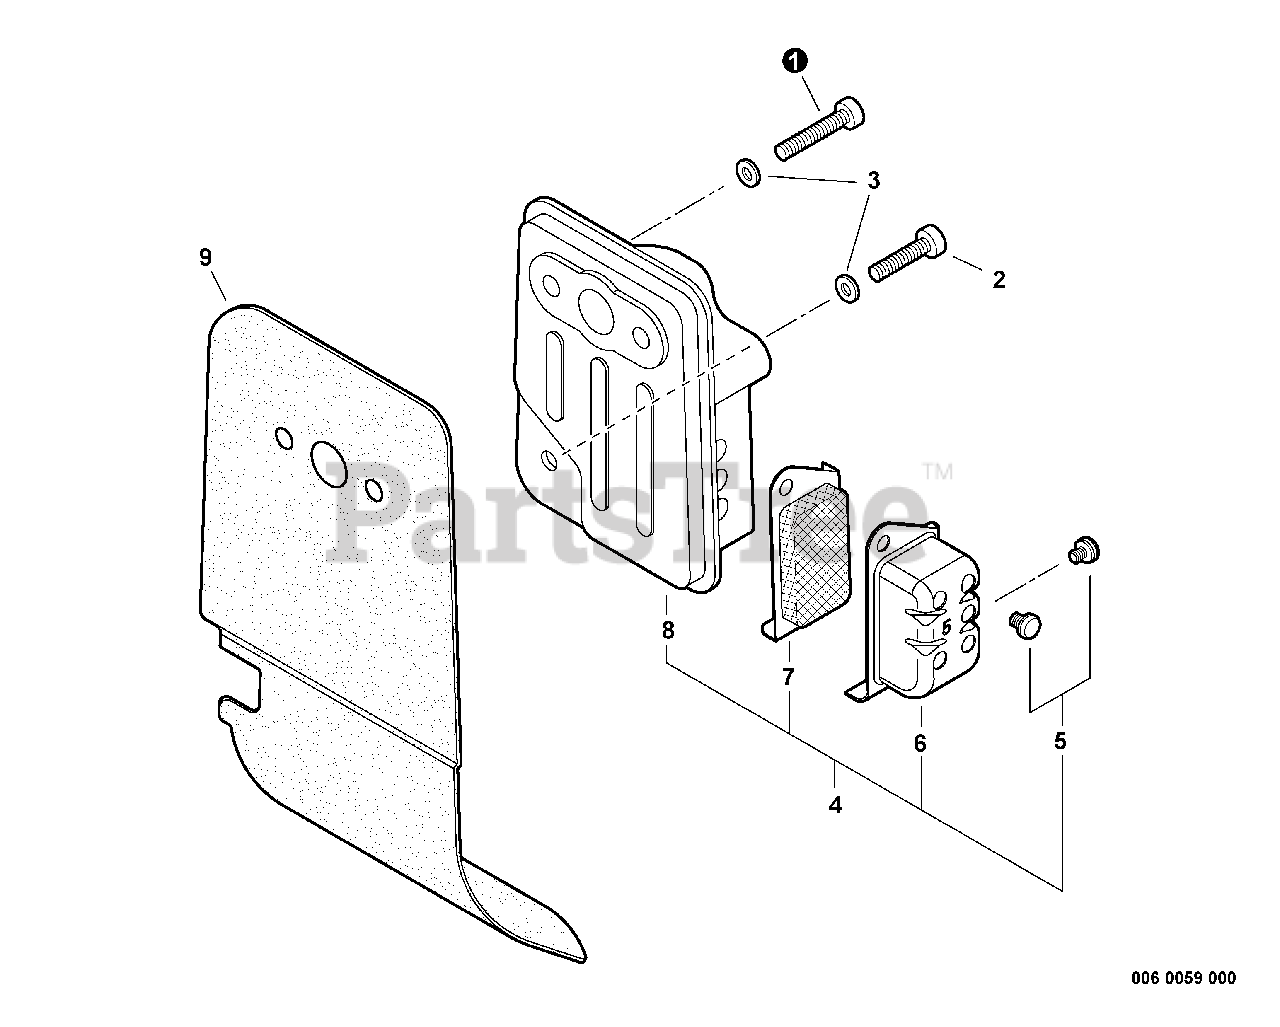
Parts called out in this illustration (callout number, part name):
1	SCREW - 5X25
2	SCREW - 5X16
3	WASHER - 5
4	MUFFLER ASSY
5	SCREW - 4X6
6	GUIDE, EXHAUST
7	SCREEN, SPARK ARRESTOR
8	MUFFLER
9	SHIELD, EXHAUST
